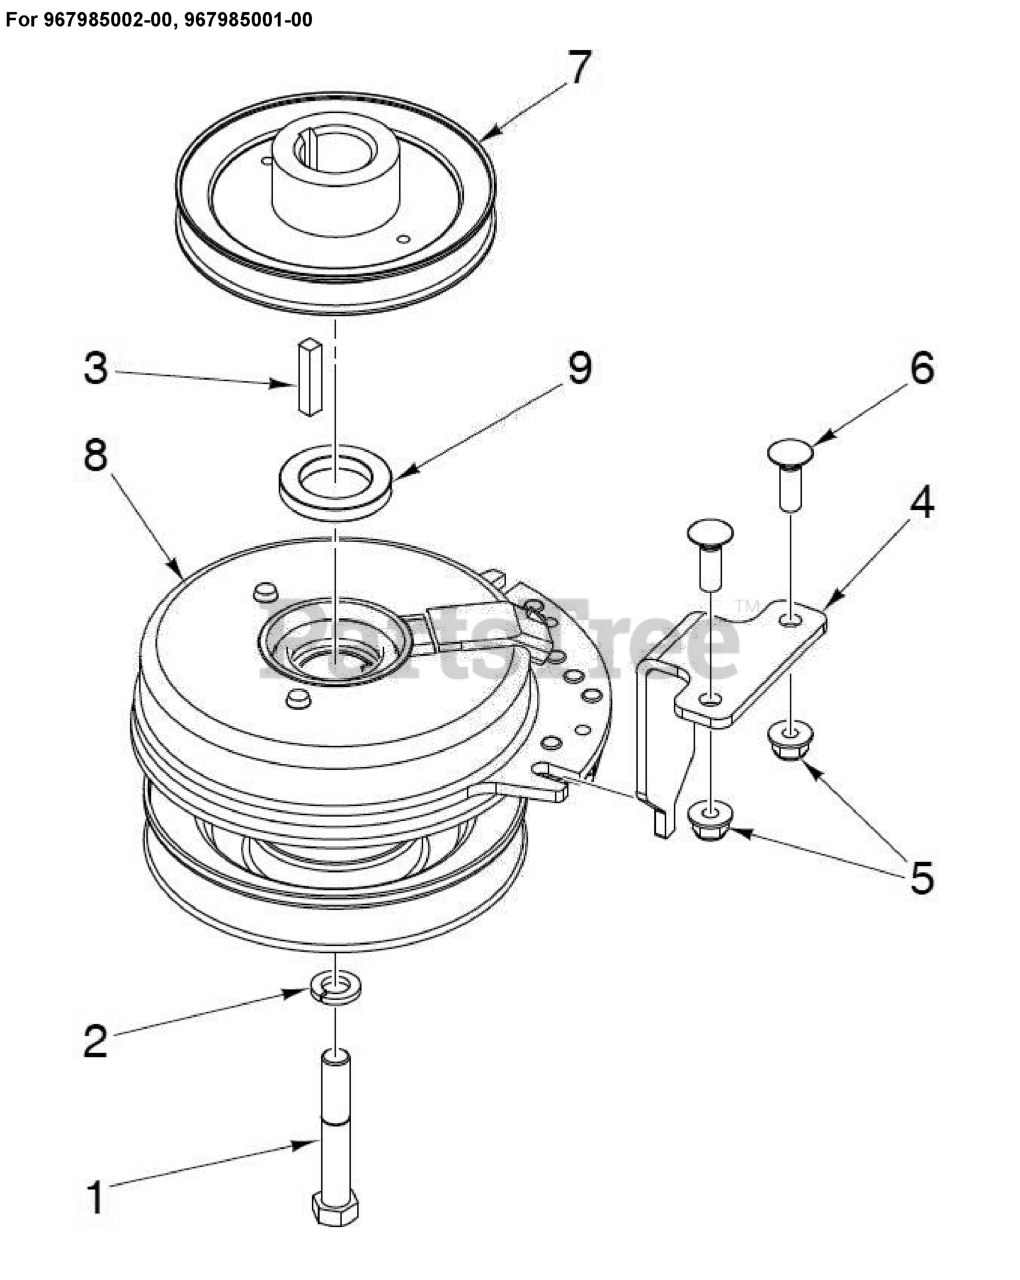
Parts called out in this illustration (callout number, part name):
3	KEY, 1/4 SQ X 1 1/4
5	NUT HEXAGON FLANGE 5/16-18 ST
7	PULLEY, V, 1.125 BORE
8	CLUTCH 200 FT LB
